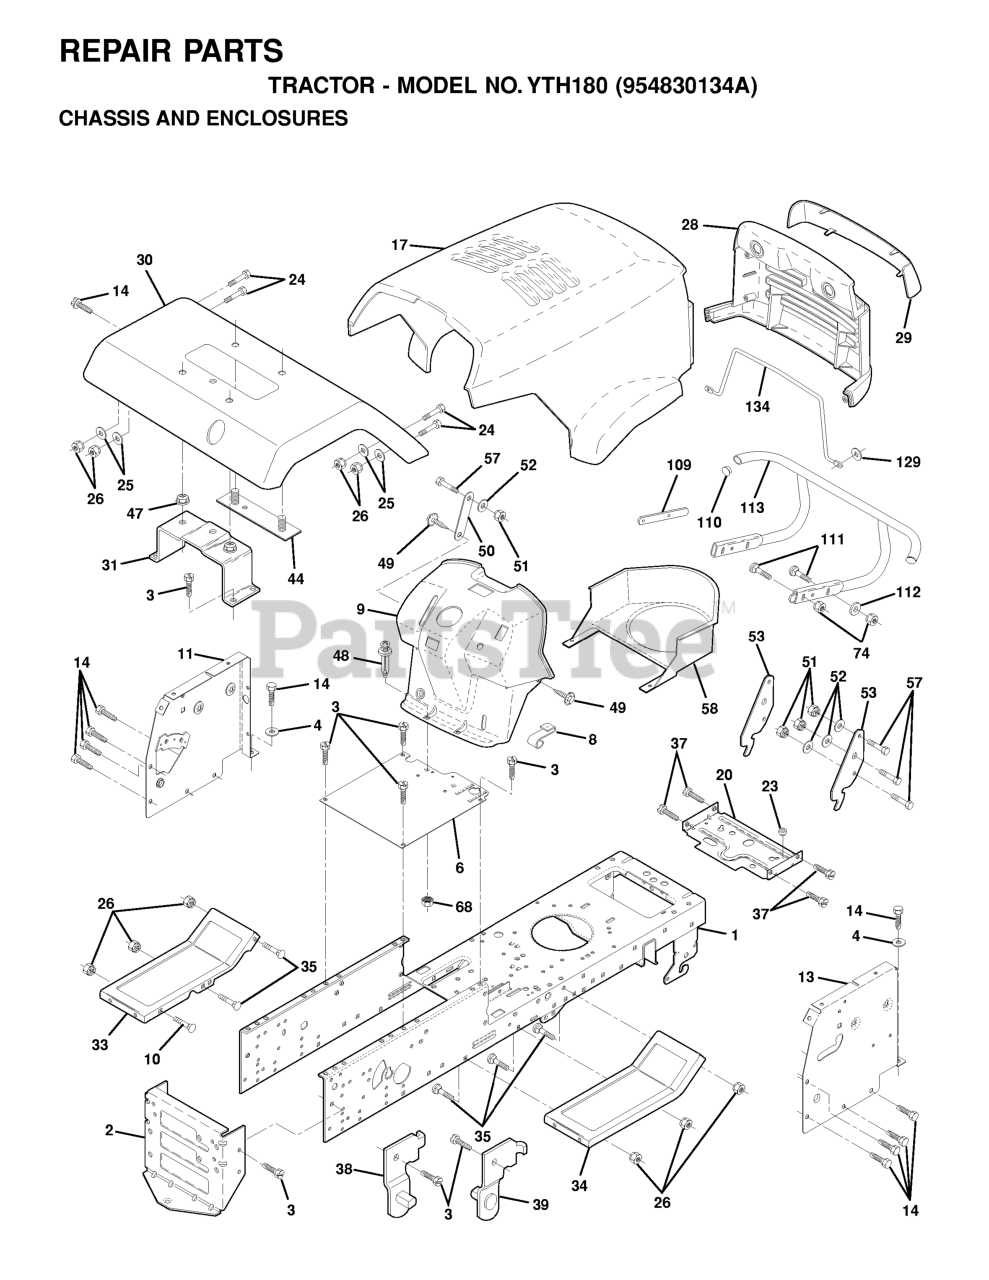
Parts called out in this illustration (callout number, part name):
1	CHASSIS WELD 11GA.95
2	STRETCH DRAWBAR
3	SCREW
4	Washer 13/32 X 3/4 X 16 Ga.
6	SADDLE LT FENDER
8	CLIP,INSULATOR
9	DASH P/L W/PTO GREY
10	BOLT D
11	PANEL PNT DASH LH
13	PANEL DASH RH
17	HOOD LT/PL HUSQVARNA
20	PLATE MTG BATTERY FUEL TAND
23	BUSHING.SNAP.NYL.BLK.
25	WASHER
26	NUT
28	GRILLE LT/PL HUSQVARNA
29	LENS LT/PL HUSQVARNA
30	FENDER YT/GT W SHIFT
31	FENDER BRKT
33	FOOTREST LT/YT/GT LH
34	FOOTREST LT/YT/GT RH
37	Screw 5/16-18 x 1/2 Hex, Self Tapping 5/16-18 x 1/2
38	BRACKET LH PIVOT
39	BRACKET RH PIVOT
44	STRAP
47	NUT-PUSH YT
48	RIVET PUSH
49	SCREW HEX CRT
51	LOCKNUT.NYLOC.1/4-20
53	BRACKET PNT PICK OFF LT/PL
57	BOLT
58	AIR DUCT P/L/LT
68	NUT
109	BRACKET BUMPER
110	PLUG PLASTIC
111	BOLT.3/8-14X1.25
112	WASHER
113	BUMPER ASM
134	ROD SUPPORT HOOD LT/PL HUSQ
